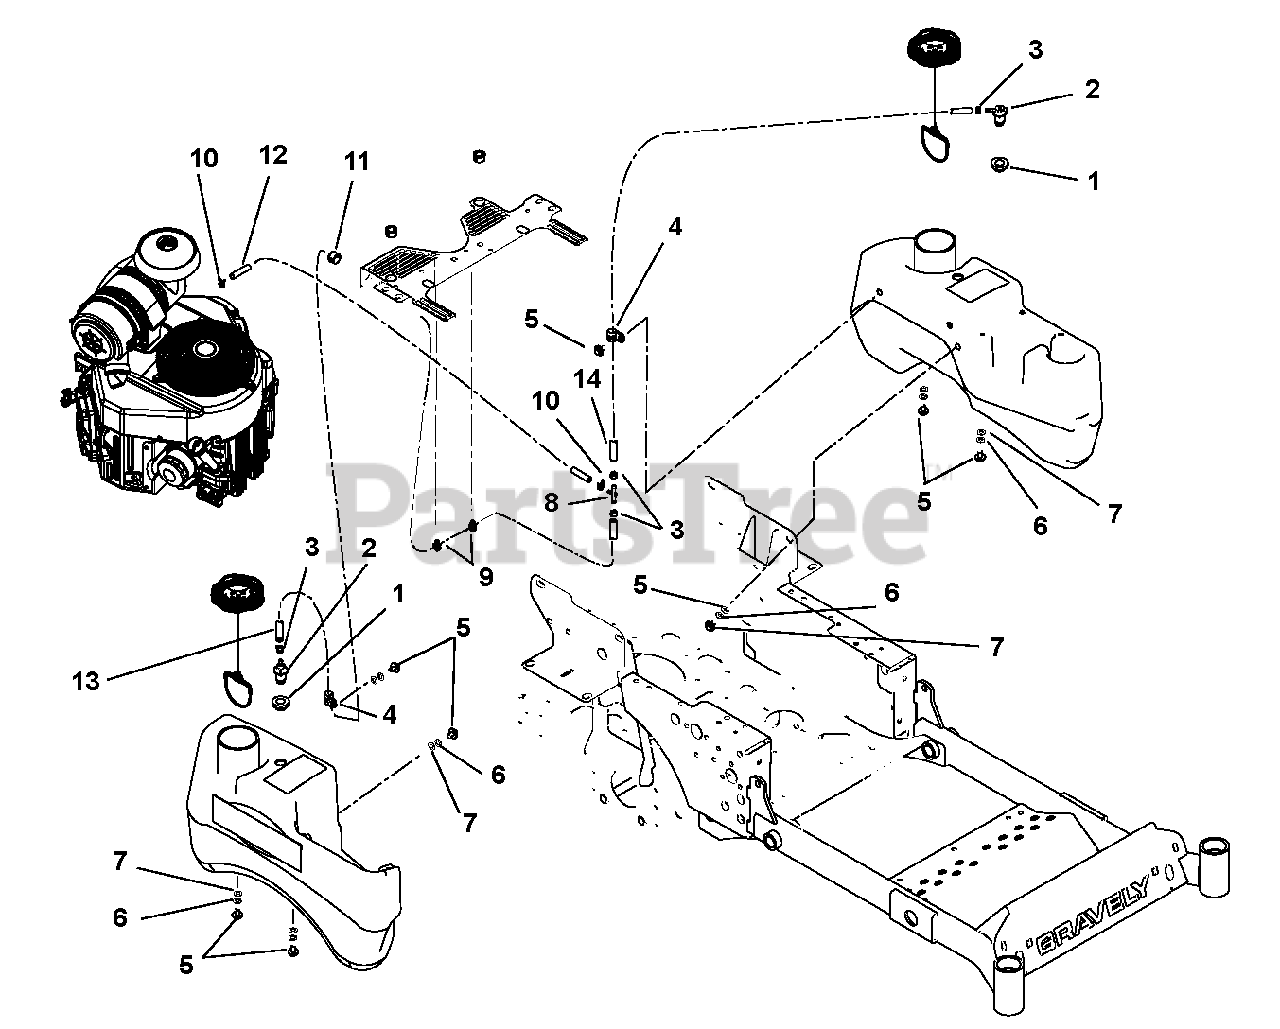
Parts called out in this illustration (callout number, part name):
2	Valve
3	Hose, Clamp
5	Bolt, .31-18 x .62
6	Washer, Locking .31 x .078 Regular
7	Washer, Flat Steel .38 x .875 x .083
8	Fitting, Tee 1/4 x 3/8
9	Clip, Routing
10	Clamp, Spring .188
11	Bushing, Snap
12	Hose, Fuel
13	Hose, Fuel
14	Hose, Fuel
